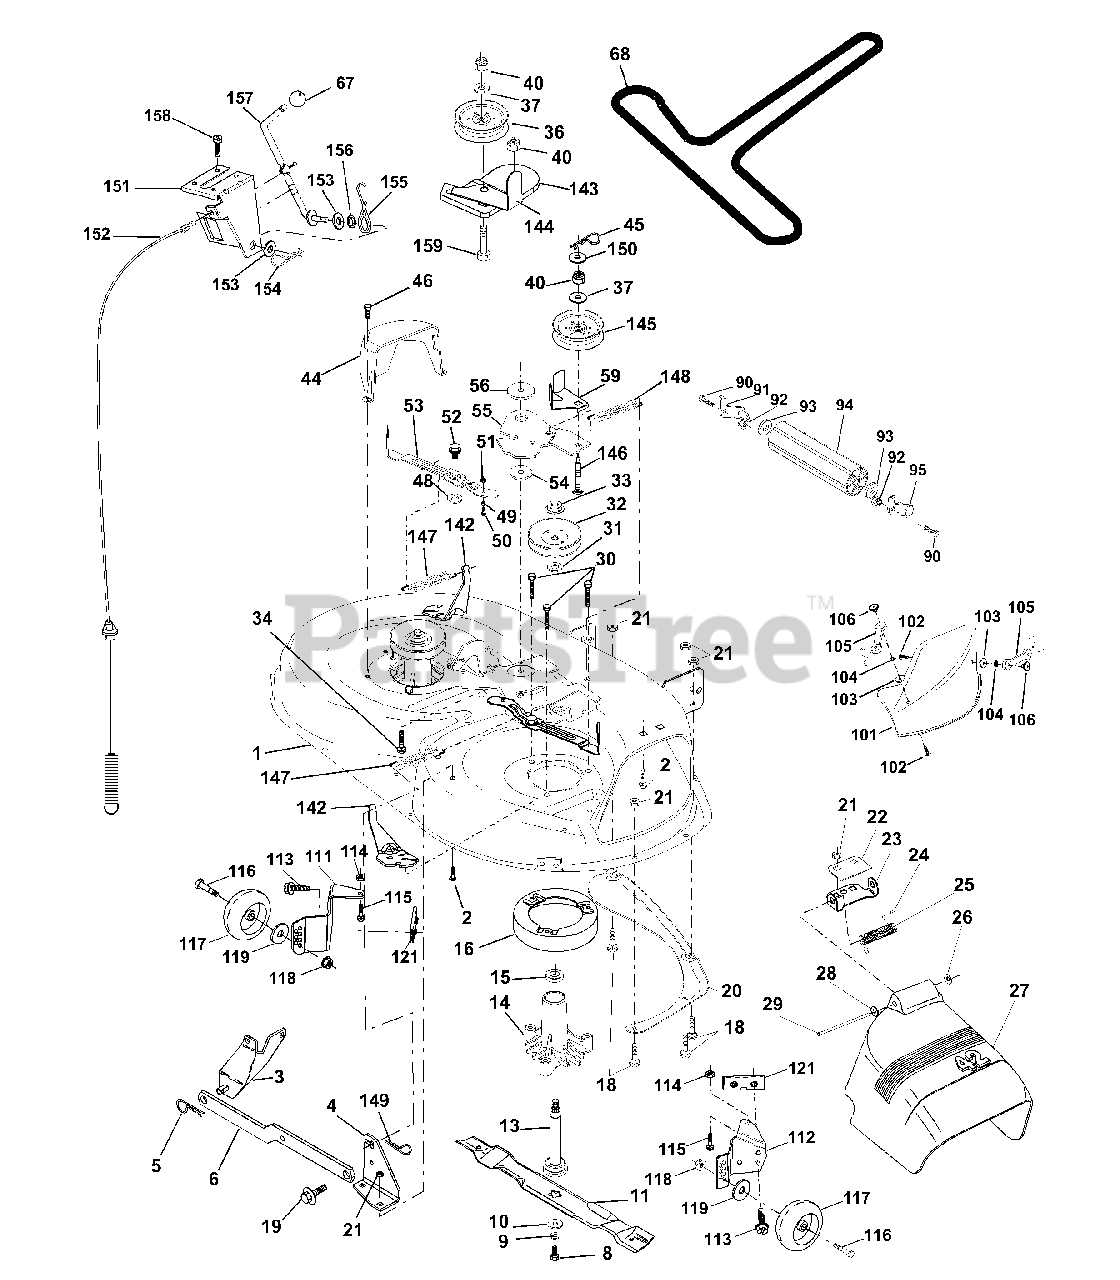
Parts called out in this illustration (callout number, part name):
1	Mower Deck Assembly, 42"
2	Bolt
3	Bracket Asm Fr. Sway Bar 3/42
4	Bracket Asm Deck 42" Sway Bar
5	Retainer Spring
6	Arm, Suspension, Rear
8	Bolt 3/8-24 x 25 Gr. 8 patched
9	Washer, Lock
10	Washer,Hardened
11	Blade, Mulching 42" Std
11	Blade Mower 42" Hi-Lift Std
13	Shaft Assembly, Mandrel, Vented
14	Housing, Mandrel, Vented
15	Bearing, Ball, Mandrel
16	Stripper, Mower Deck
18	Bolt, Carriage 5/16-18 x 5/8
19	Bolt, Shoulder
20	Baffle, Vortex
21	Nut
22	Stiffener Bracket
23	Bracket, Deflector Mower 42"
24	Cap, Sleeve 80 x 112 Blk Mower
25	Spring, Torsion, Deflector 2 52
26	Nut, Push Phos & Oil
27	Shield, Deflector 42" Blk
28	Washer 11/32 x 5/8 x 16 Ga.
29	Rod, Hinge 42" 6 75 W/G
30	Screw Thdrol Washer Head
31	Washer, Spacer Mower Vented
32	Pulley, Mandrel
33	Nut, Toplock 9/16
34	Bolt
36	Pulley, Idler, Flat
37	Washer 13/32 x 13/16 x 16 Ga.
40	Nut
44	Guard, Mandrel, LH
45	Retainer
46	Screw, Thdrol 1/4-20 x 5/8 T
48	Washer,Hardened
49	Roller Assembly, Cam Follower
50	Bolt, Shoulder #10-24 Grade 5
51	Locknut
52	Bolt, Shoulder 5/16-18 Unc
53	Arm Assembly, Pad, Brake
54	Washer,Hardened
55	Arm, Idler
56	Spacer, Retainer
59	Guard TUV Idler
67	Knob Round
68	V-Belt, 42" Mower
90	Bolt Fin Hex 3/8-16 Unc x 1
91	Bracket Asm Noseroller LH
92	Nut, Lock, Hex W/Ins 3/8-16 Unc
93	Washer 17/3 x 7/8 x 6 Ga.
94	Roller Nose 38 & 42
95	Bracket Asm Noseroller RH
101	Mulcher Cover
102	Screw Pan Hd Phillips 10-24 x 5/8
103	Washer, Flat
104	Washer, Lock
105	Latch Assembly
106	Nut, Weld
111	Bracket, Ga., Wheel LH
112	Bracket, Ga., Wheel RH
113	Screw 5/16 - 18
114	Nut, Keps 5/16 - 18 Unc
115	Bolt, Carriage 5/16-18 x 1/2
116	Bolt, Shoulder
117	Wheel, Ga.
118	Nut Centerlock 3/8-16
119	Washer 3/8 x 7/8 x 14 Ga.
121	Bracket, Extruded
142	Arm Spring Brake Mower
143	Bracket Arm Idler 42"
144	Keeper Belt 42" Clutch Cable
145	Pulley Idler Flat
146	Bolt Carriage Idler
147	Spring Extension
148	Spring Return Idler
149	Retainer Spring Yellow
150	Washer 9/32 x 3/4 x 16 Ga.
151	Bracket Clutch Cable
152	Clutch Cable 42"
153	Washer Flat 3/8" Type B
154	Spring Retainer
155	Spring Retention LVR CLTCH CAB
156	Spacer Clutch Cable
157	Rod Clutch Cable 3/8"
158	Screw Hex Thd Cut 1/4-20 x 5/8
159	Bolt Rdhd Sqn 3/8-16 UNC x 1-3/4
